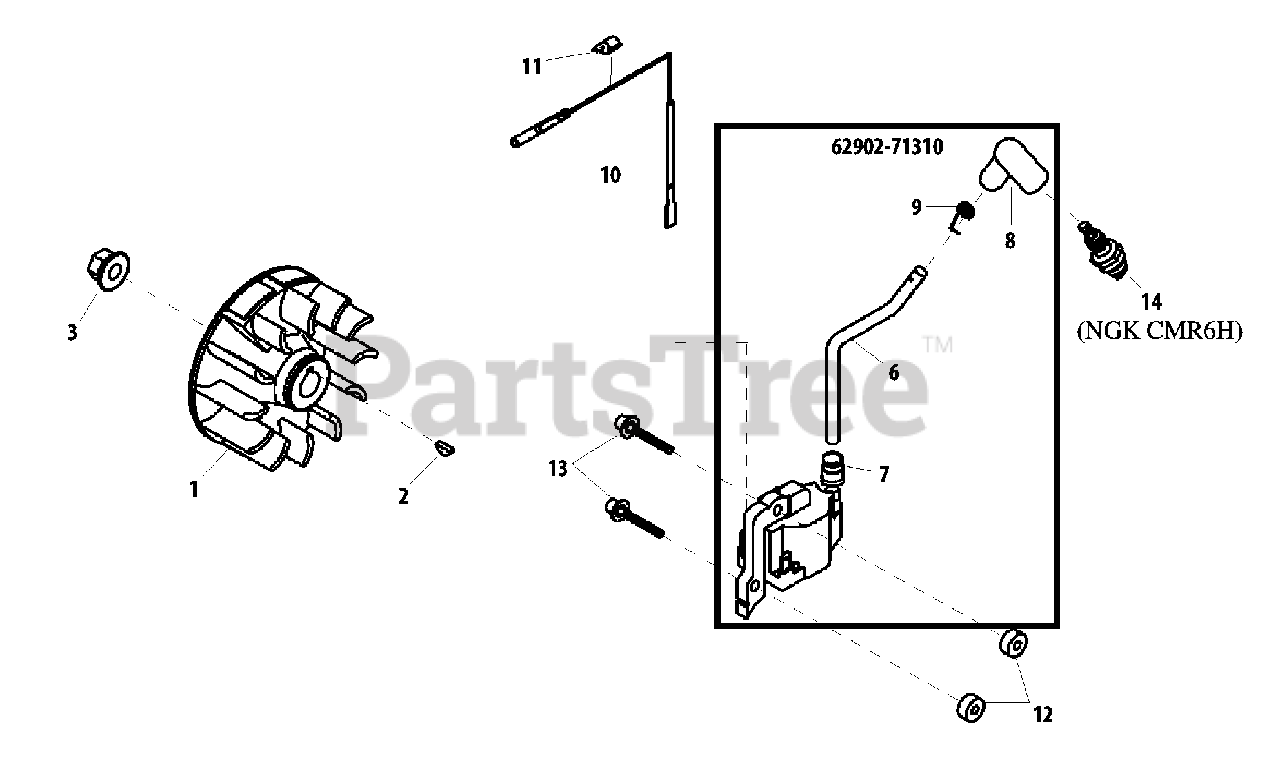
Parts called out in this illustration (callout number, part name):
1	FLYWHEEL
2	KEY, WOODRUFF 3×10
3	NUT M8
7	GROMMET
8	CAP, SPARK PLUG
9	TERMINAL, SPARK PLUG
10	LEAD
11	GROMMET, LEAD
12	INSULATOR 4.2×11×6
13	BOLT M4×26
14	SPARK PLUG
62902-71310	IGNITION COIL ASSY
